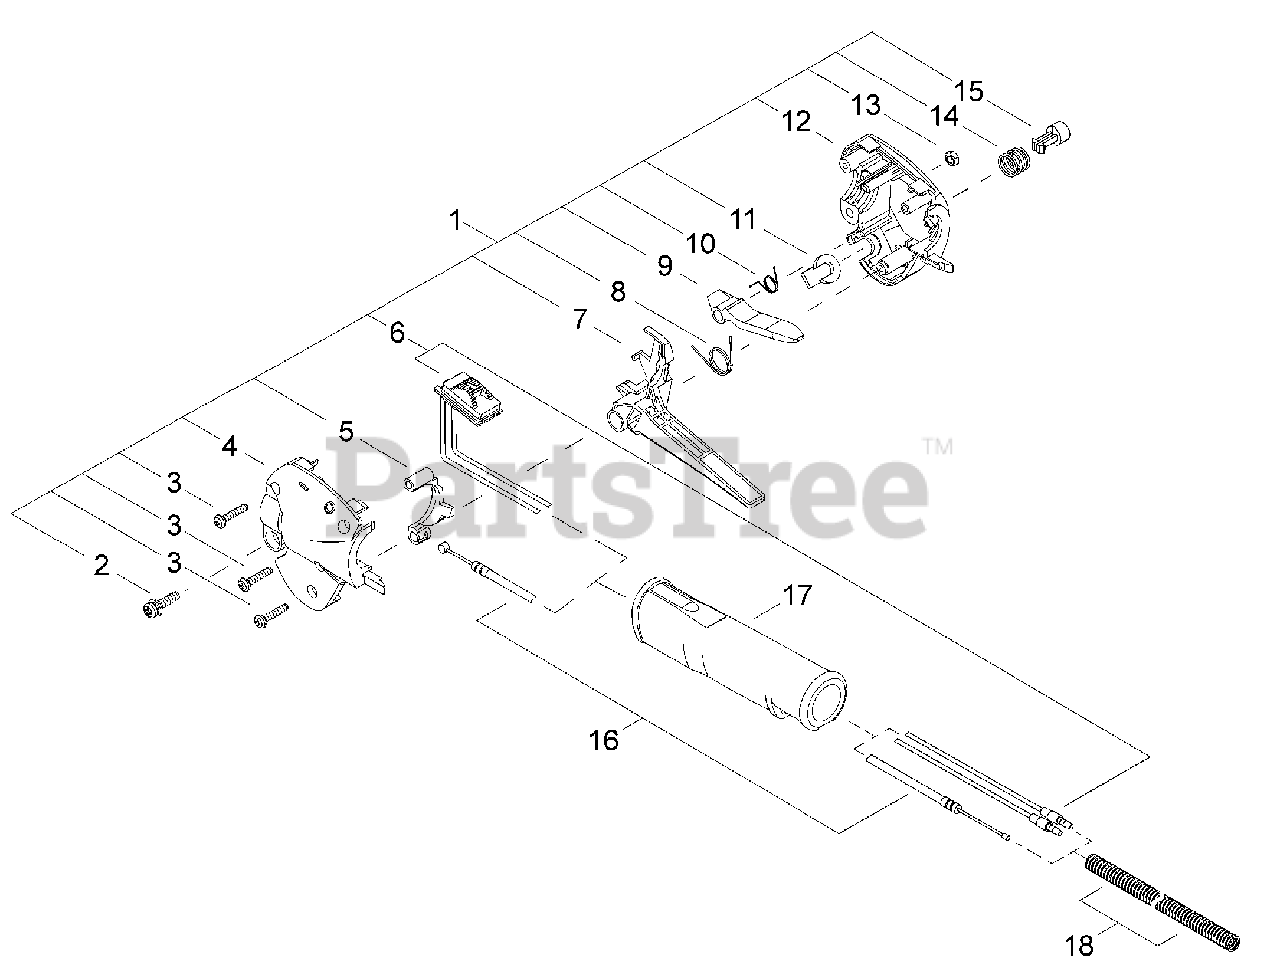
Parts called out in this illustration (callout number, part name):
1	THROTTLE LEVER ASSY
2	SCREW - 5X20
3	SCREW - 4X20 -- TAPPING
4	HANDLE, CONTROL - LEFT
5	LOCKOUT, THROTTLE
6	SWITCH, IGNITION
7	TRIGGER, THROTTLE
8	SPRING
9	LEVER, TRIGGER LOCKOUT
10	SPRING
11	PLUG
12	HANDLE, CONTROL - RIGHT
13	NUT - 5
14	SPRING
15	BUTTON, THROTTLE LOCK
16	CABLE, THROTTLE
17	GRIP - REAR
18	TUBE
